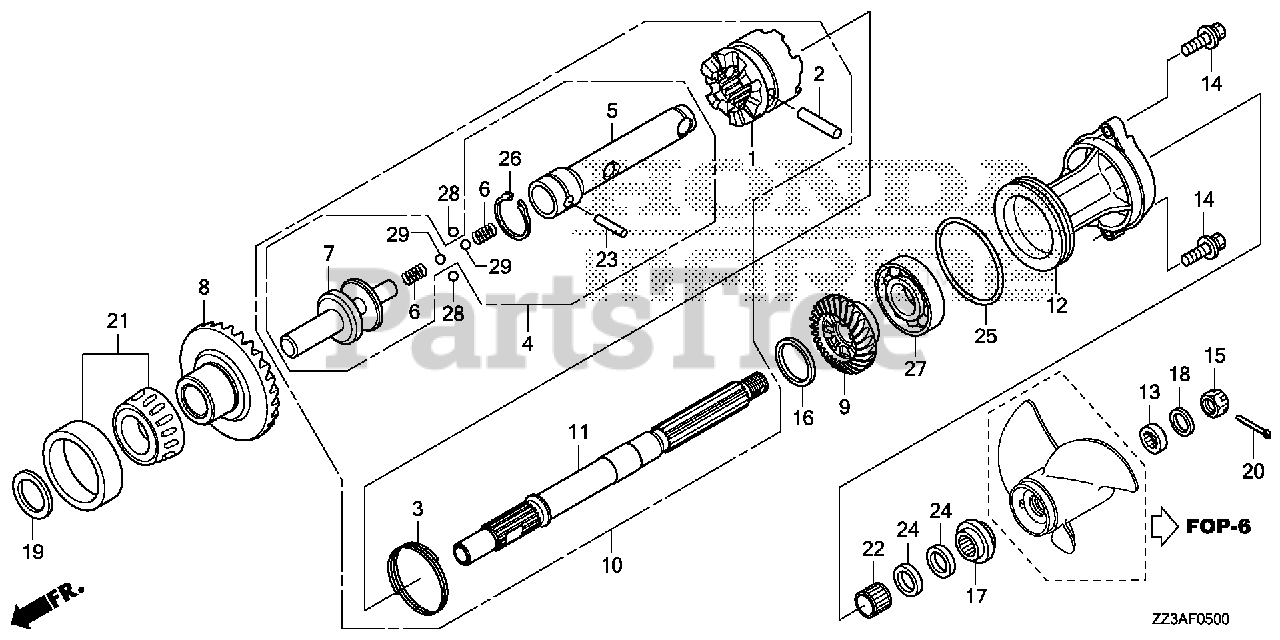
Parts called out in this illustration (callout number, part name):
1	SHIFTER, CLUTCH
2	PIN, SHIFTER (6.3X33)
3	RING, CROSS PIN
4	SLIDER, SHIFT
5	SLIDER, SHIFT
6	SPRING, SHIFT
7	PLATE, SHIFT
8	GEAR, FR. BEVEL (29T)
9	GEAR, RR. BEVEL (29T)
10	SHAFT ASSY., PROPELLER
11	SHAFT, PROPELLER
12	HOLDER, PROPELLER SHAFT *NHB14M* (AQUA MARINE SILVER METALLIC)
13	SPACER (10MM)
14	BOLT-WASHER (8X30)
15	NUT, CASTLE (16MM)
16	WASHER (22MM)
17	WASHER, PROPELLER THRUST
18	WASHER (17MM)
19	SHIM, FR. BEVEL (51X57X0.10) (A)
19	SHIM, FR. BEVEL (51X57X0.15) (B)
19	SHIM, FR. BEVEL (51X57X0.30) (C)
19	SHIM, FR. BEVEL (51X57X0.50) (D)
20	PIN, SPLIT (4.0)
21	BEARING (32X58X17)
22	BEARING, NEEDLE (22X28X20)
23	ROLLER (3X12.8)
24	SEAL, WATER (22X35X7)
25	O-RING (76.5X3)
26	CIRCLIP (14MM)
27	BEARING, RADIAL BALL (6007)
28	BALL, STEEL (#6) (3/16)
29	BALL, STEEL (#7) (7/32)
